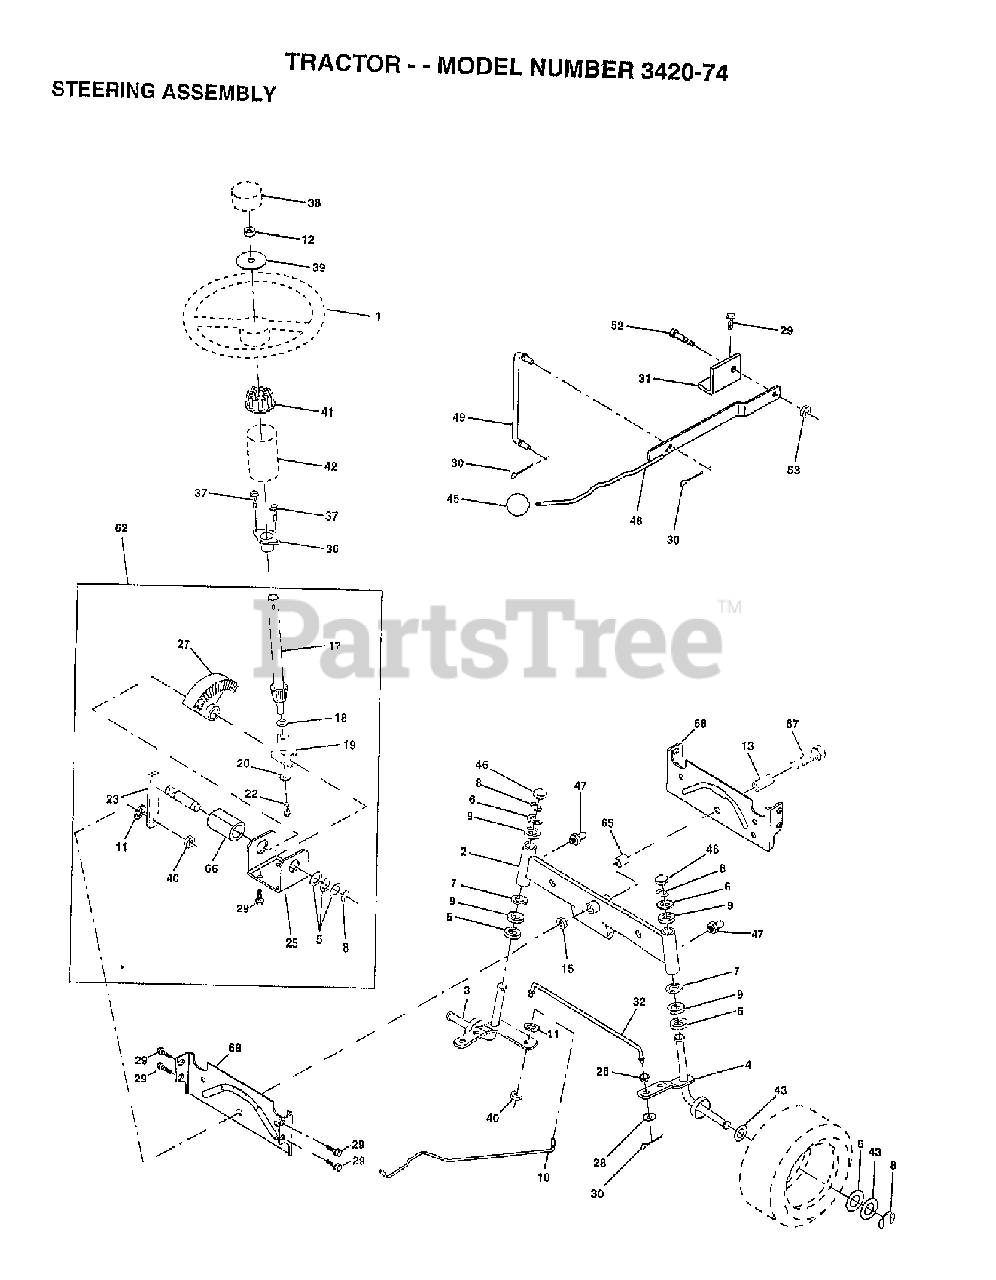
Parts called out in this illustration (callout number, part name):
1	Steering Wheel
2	Half Axle Assembly, Welded
3	SPINDLE.ASM.LH
5	WASHER THRUST
8	RING CLIP
9	BEARING.STEERING.COLUMN
10	DRAGLINK-STAMPED
11	WASHER, LOCK 3/8
12	NUT.HEX.1/2-20
13	BEARING AXLE
15	LOCK NUT
17	STEERING SHAFT
18	THRUST WASHER
19	SHAFT,SUPPORT
20	WASHER
23	SHAFT,PITMAN
25	BRACKET STEERING
26	BUSHING STEERING
27	GEAR.SECTOR
28	WASHER
30	COTTER PIN
36	BUSHING STRG 3/4
37	SCREW.TT.#10-32X.5.3/8.FLANGE
38	INSERT STR WHL
40	NUT
46	CAP.SPINDLE.BLACK
47	ZERK.GREASE.TAPERED
62	STEERING KIT
65	SPACER AXLE
66	BEARING ARM
67	BOLT.HEX.FINISHED.5/8
68	AXLE, BRACE
